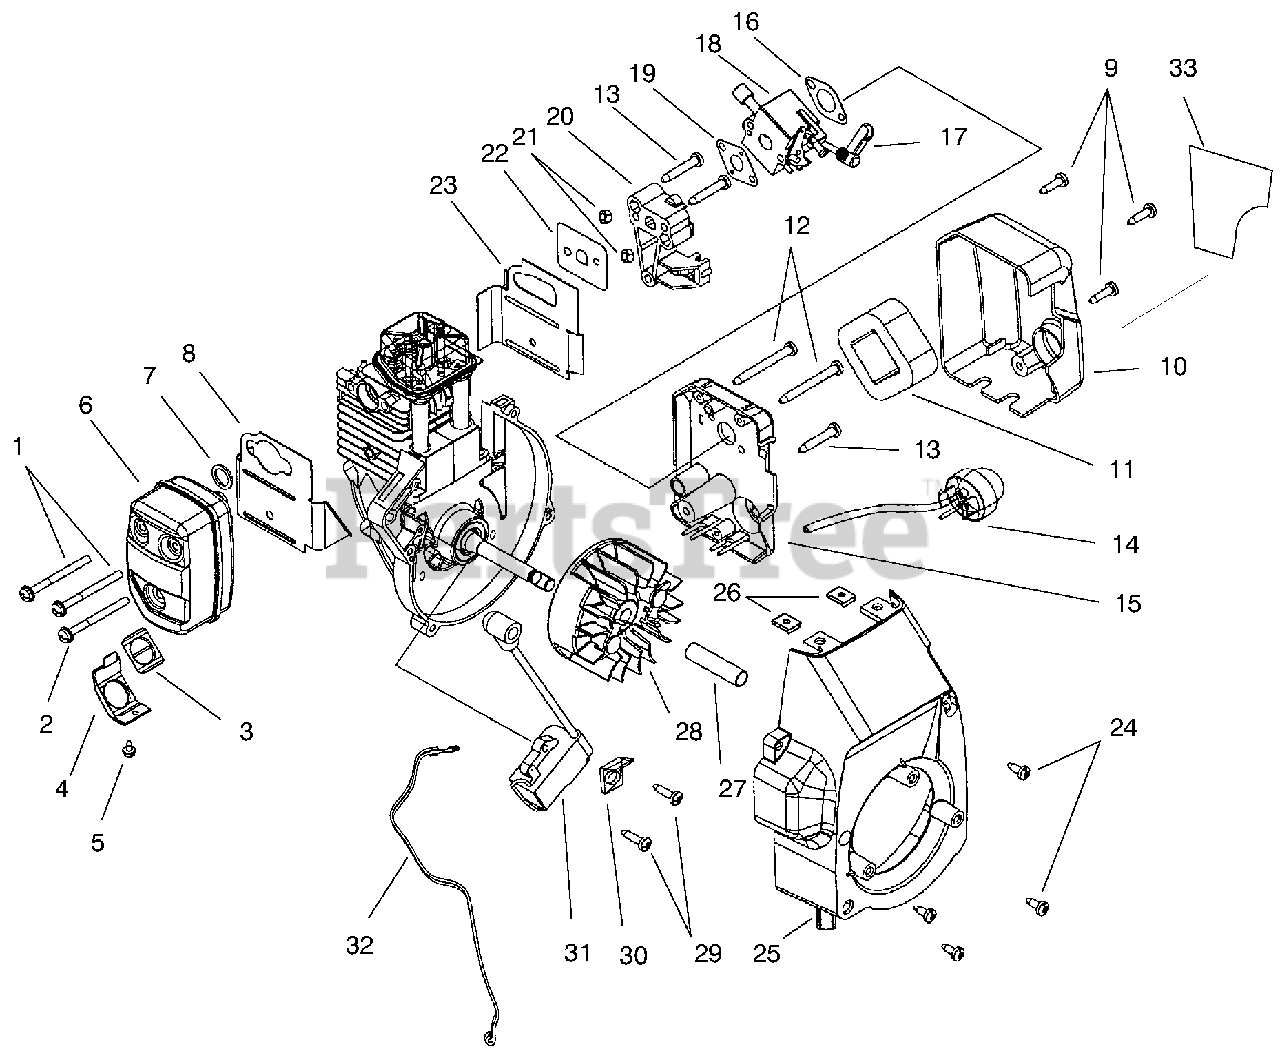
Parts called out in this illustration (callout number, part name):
1	Screw-Muffler Mounting
2	Screw-Muffler Mounting
3	Screen-Spark Arrestor
4	Cover-Screen
5	Screw-Screen Cover
6	Muffler (Incl. Ref. #1-5 & 7)
7	Gasket-Muffler
8	Baffle-Muffler
9	Screw-Air Filter Cover
10	Cover-Air Filter
11	Filter-Air
12	Screw-Air Filter Base
14	Primer & Line Assembly
15	Base-Air Filter
17	Lever-Choke
18	Carburetor W/Choke Lever
20	Insulator-Carb. Mount
21	Nut-Hex
22	Gasket-Intake
23	Baffle-Intake
25	Housing-Fan
26	Nut-Tinnerman
28	Flywheel
29	Screw-Module
30	Tab-Ground
31	Module-Ignition
32	Lead-Wire 18"
33	Decal-Choke
